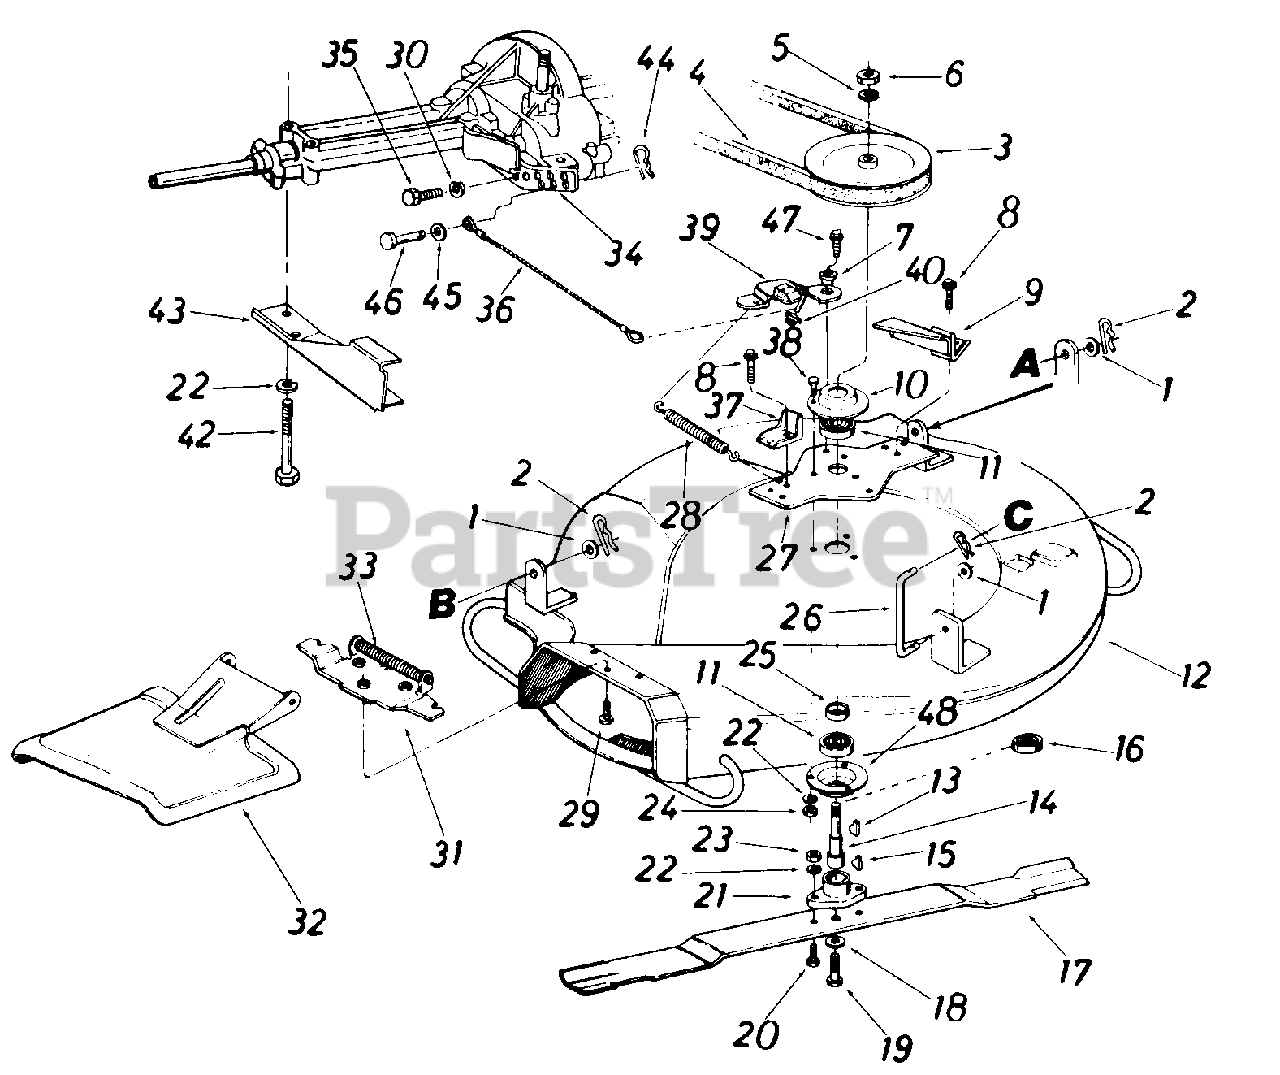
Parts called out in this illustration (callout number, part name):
1	Fl-Wash. .385" I.D. x .87" O.D. x .06
2	Cotter Pin 118" Dia. x 1.00"
3	Deck Pulley 6.0" O.D.
4	"V"-Belt 1/2" x 52" Lg.
5	Fl-Wash. 5/8" I.D.
6	Hex Jam Nut 5/8-11 Thd.
7	Shoulder Spacer
8	Hex Wash. Hd. Scr. 5/16-18 x.62" Lg.
9	Belt Guard Ass'y.
10	Bearing Housing 1.85" I.D.
11	Ball Brg. .787" I.D. x 1.85" O.D. x .551
12	26n Deck Ass'y.
13	#61 Hi-Pro Key 3/16" x 5/8" Dia.
14	Blade Spindle
15	#6 Hi-Pro Key 5/32" x 5/8" Dia.
16	Bearing Shield
17	26" Blade
18	L-Wash. 3/8" I.D.-H.D.
19	Hex Bolt 3/8-24 x 1.50" Lg. (Grade 5)
20	Hex Bolt 5/16-24 x 1.00" Lg. (Grade 5)
21	Blade Adapter Kit
22	L-Wash. 5/16" I.D.
23	Hex Nut 5/16-24 Thd.
24	Hex Nut 5/16-18 Thd.
25	Spacer.836" I.D. x 1.01" O.D. x .320
26	Deck Link 3.9" Lg.
27	Belt Guard Plate Ass'y.
28	Spring .38" O.D. x 3.25" Lg.
29	Hex Self-Tap Scr. 1/4" x .50" Lg.
30	L-Wash. 1/4" I.D.
31	Adapter Ass'y.-Chute
32	Chute Deflector Ass'y. Comp.
33	Torsion Spring
34	Lower Inside Belt Guard
35	Hex Bolt 1/4-20 x .62" Lg.
36	Brake Cable Ass'y.
37	Belt Keeper Ass'y.
38	Hex Sems Bolt 5/16-18 x 1.00" Lg.*
39	Blade Brake Brkt. Ass'y.
40	Cap Speed Nut 1/4" Rod
42	Hex Bolt 5/16-18 x 2.75"*
43	Lower Outside Engine Belt Guard
44	Hairpin Cotter
45	Fl-Wash. 1/4" I.D. x .50" O.D.
46	Clevis Pin 1/4" x 1/2"
47	Self-Tap Scr. 3/8 x .75" Lg.
48	Open Brg. Housing 1.85"
